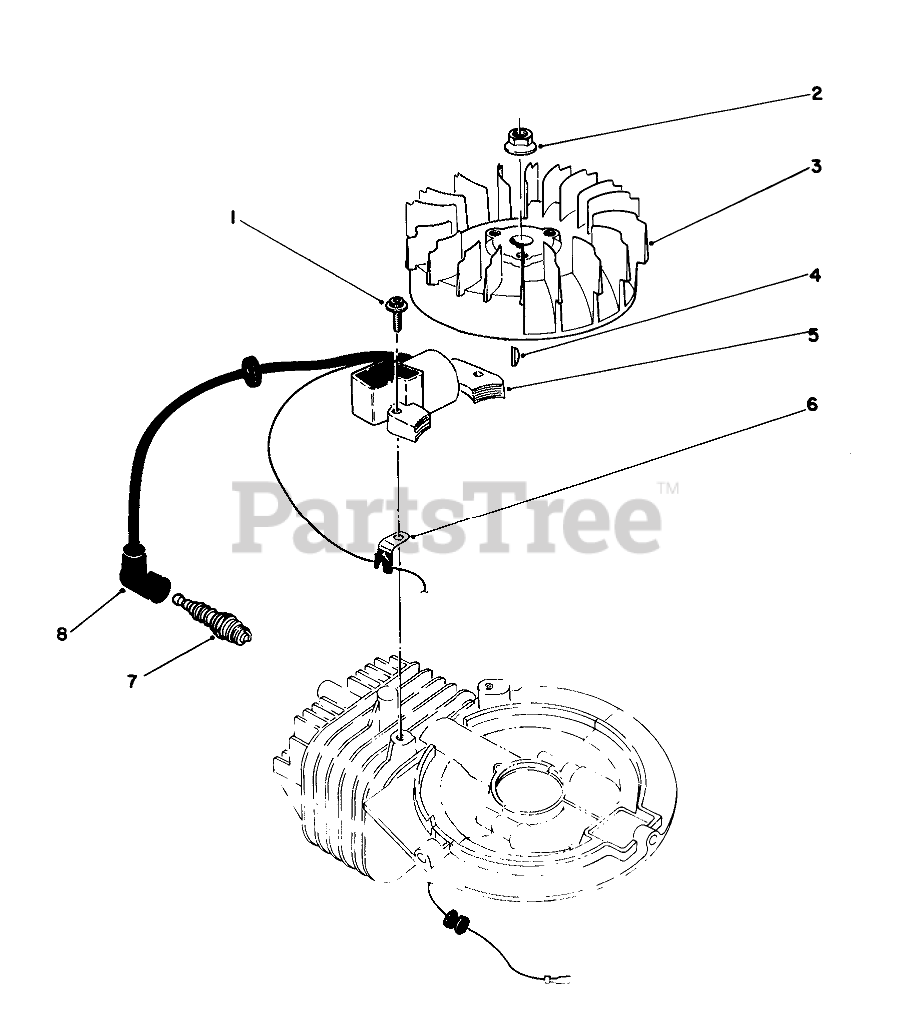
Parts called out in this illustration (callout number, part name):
1	Allenhead
3	FLYWHEEL
5	COIL-MAGNETO
6	CLAMP
7	Sparkplug
8	CAP-SPARKPLUG
